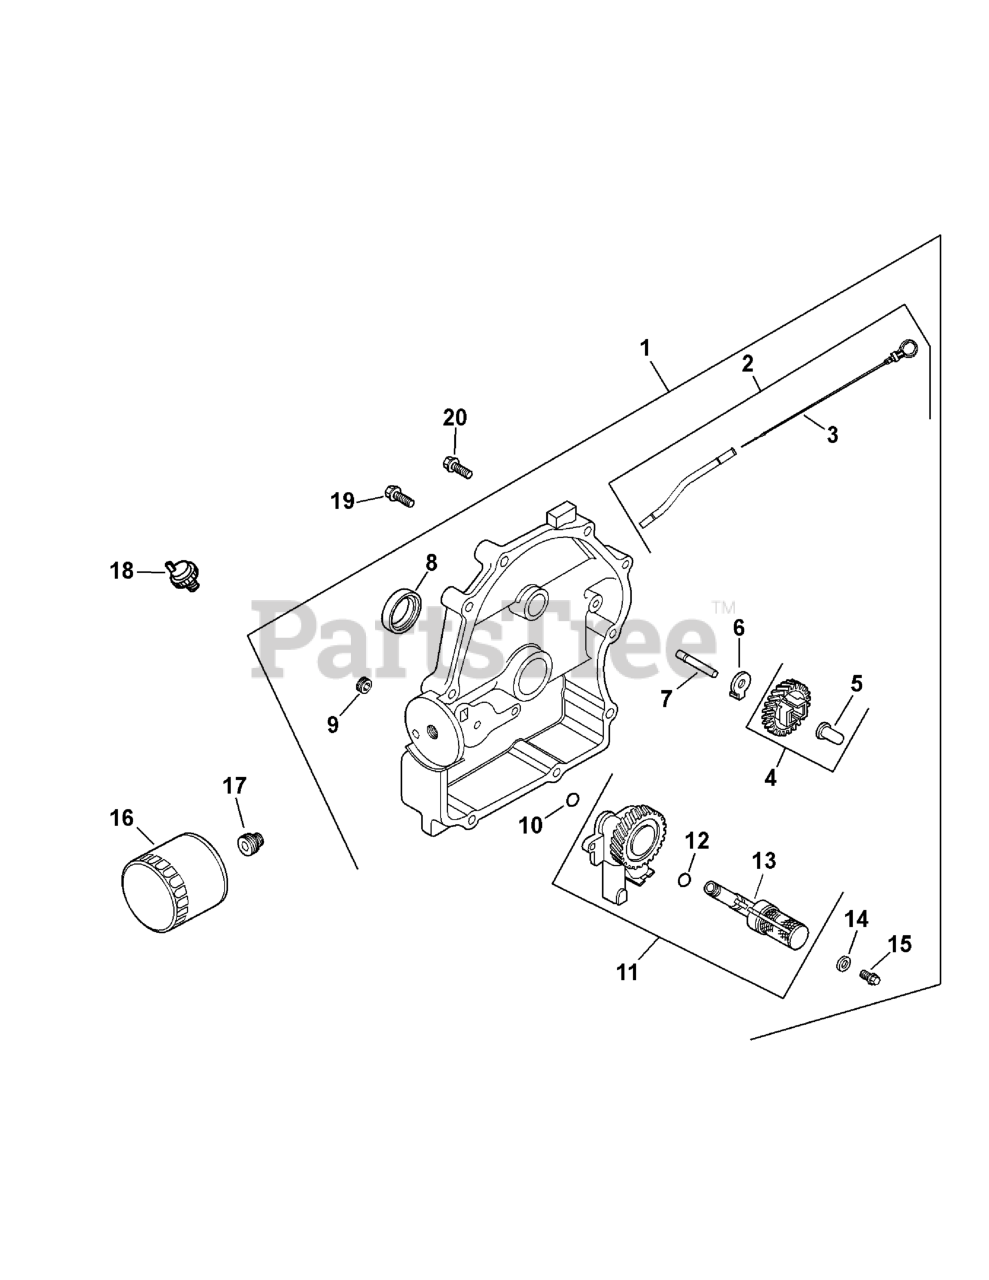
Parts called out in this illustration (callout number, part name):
1	Plate, closure ass’y
2	Kit, tube w/dipstick
4	Kit, governor gear
5	Pin, governor regulating
7	Shaft, governor gear
8	Seal, oil (PTO end)
9	Plug, pipe 1/8"
11	Oil pump ass’y
12	O-Ring, oil pick-up
13	Pick-up, oil
14	Washer, plain 6 mm
15	Screw, hex flange M6x1.0x25
17	Nipple, oil filter
18	Switch, pressure
19	Screw, hex g, M8x1.25x45
20	Screw, hex. flange M8x1.25x45
